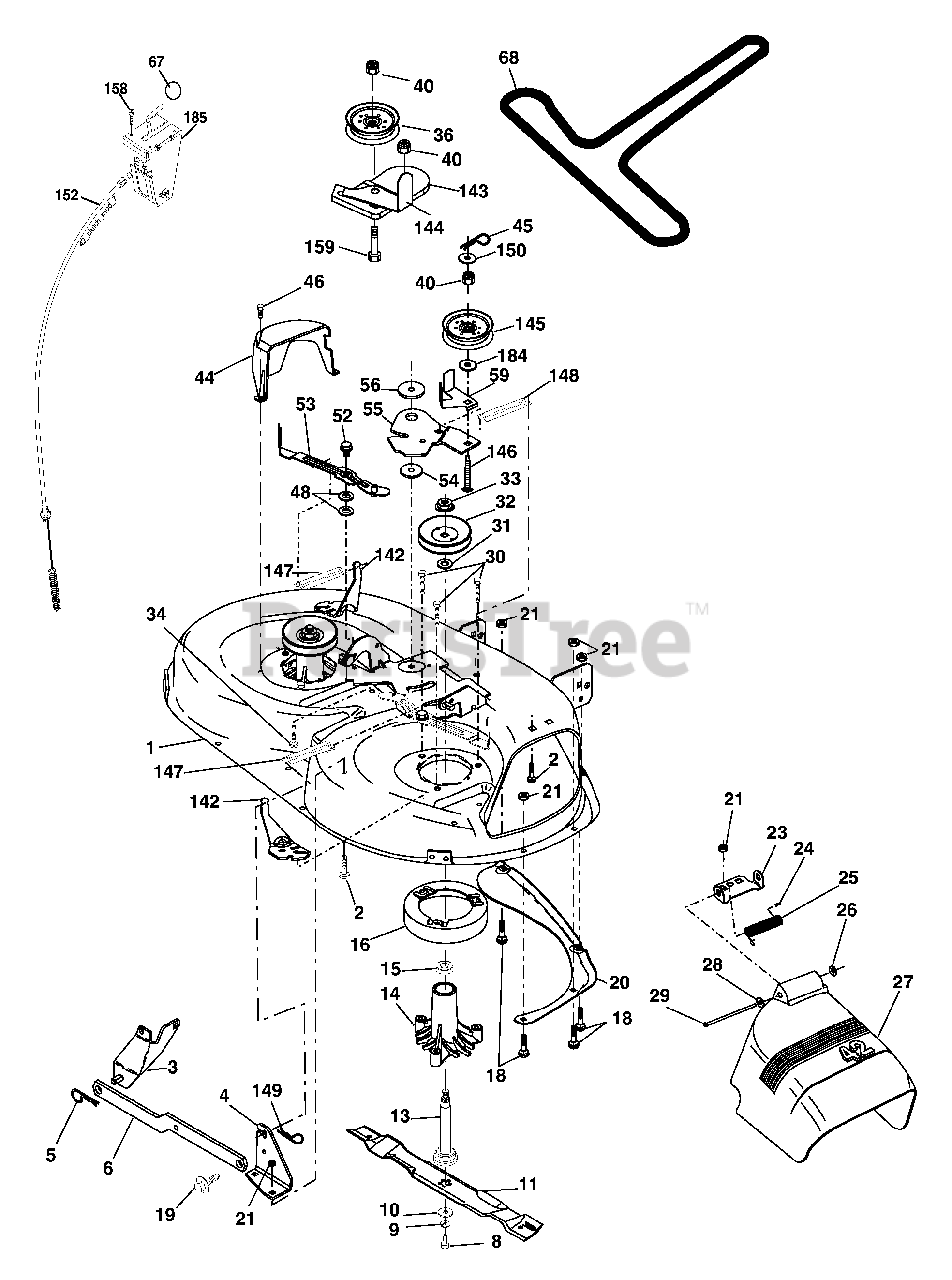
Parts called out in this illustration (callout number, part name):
1	Mower Deck Assembly, 42"
2	Bolt 5/16-18 x 3/4
3	Bracket Assembly,Sway Bar, Front
4	Bracket Sway Bar 38/42" eck
5	Retainer Spring
6	Bar Sway Deck
8	Bolt, Hex 3/8-24 x 1.25 Gr. 8
9	Washer, Lock
10	Washer, Hardened
11	Blade, 42" Hi-Lift
11	Blade, Mulching Std.
11	Blade, 42" Mulching Premium
13	Shaft Assembly, Mandrel, Vented
14	Housing, Mandrel, Vented
15	Bearing, Ball, Mandrel
16	Stripper, Mower Deck
18	Bolt, Carriage 5/16-18 x 5/8
19	Bolt, Shoulder
20	Baffle, Vortex
21	Nut Crownlock 5/16-18 unc
23	Bracket, Deflector
24	Cap, Sleeve
25	Spring, Torsion, Deflector
26	Nut, Push
27	Shield, Deflector
28	Washer 11/32 x 5/8 x 16 Ga.
29	Rod, Hinge
30	Screw Thdrol DOD PT Hex
31	Washer, Spacer
32	Pulley, Mandrel
33	Nut, Toplock, Flanged
34	Bolt Carr. Sh. 3/8-16 x 1-1/2 Gr. 5
36	Pulley, Idler, Flat
40	Nut Lock Flg. 3/8-16 unc
44	Guard, Mandrel, L.H.
45	Retainer
46	Screw, Thd. Roll 1/4-20 x 5/8
48	Washer, Hardened
52	Bolt, Shoulder 5/16-18 unc
53	Arm Assembly, Pad, Brake
54	Washer, Hardened
55	Arm, Idler
56	Spacer, Retainer
59	Guard, TUV Idler
67	Knob Custom Oval
68	V-Belt
142	Arm Spring Brake Mower
143	Bracket Arm Idler 42"
144	Keeper Belt 42" Clutch Cable
145	Pulley Idler Flat
146	Bolt Carriage Idler
147	Spring Extension
148	Spring Return Idler
149	Retainer Spring Yellow Zinc
150	Washer 9/32 x 3/4 x 10 Ga.
152	Cable Clutch 42 In
158	Screw Hex Thd Cut 1/4-20 x 1/2
159	Bolt Rdhd Sqn 3/8-16 unc x 1-3/4
184	Washer 13/32 x 7/8 x 10 Ga.
185	Head Assy. Cable Clutch
